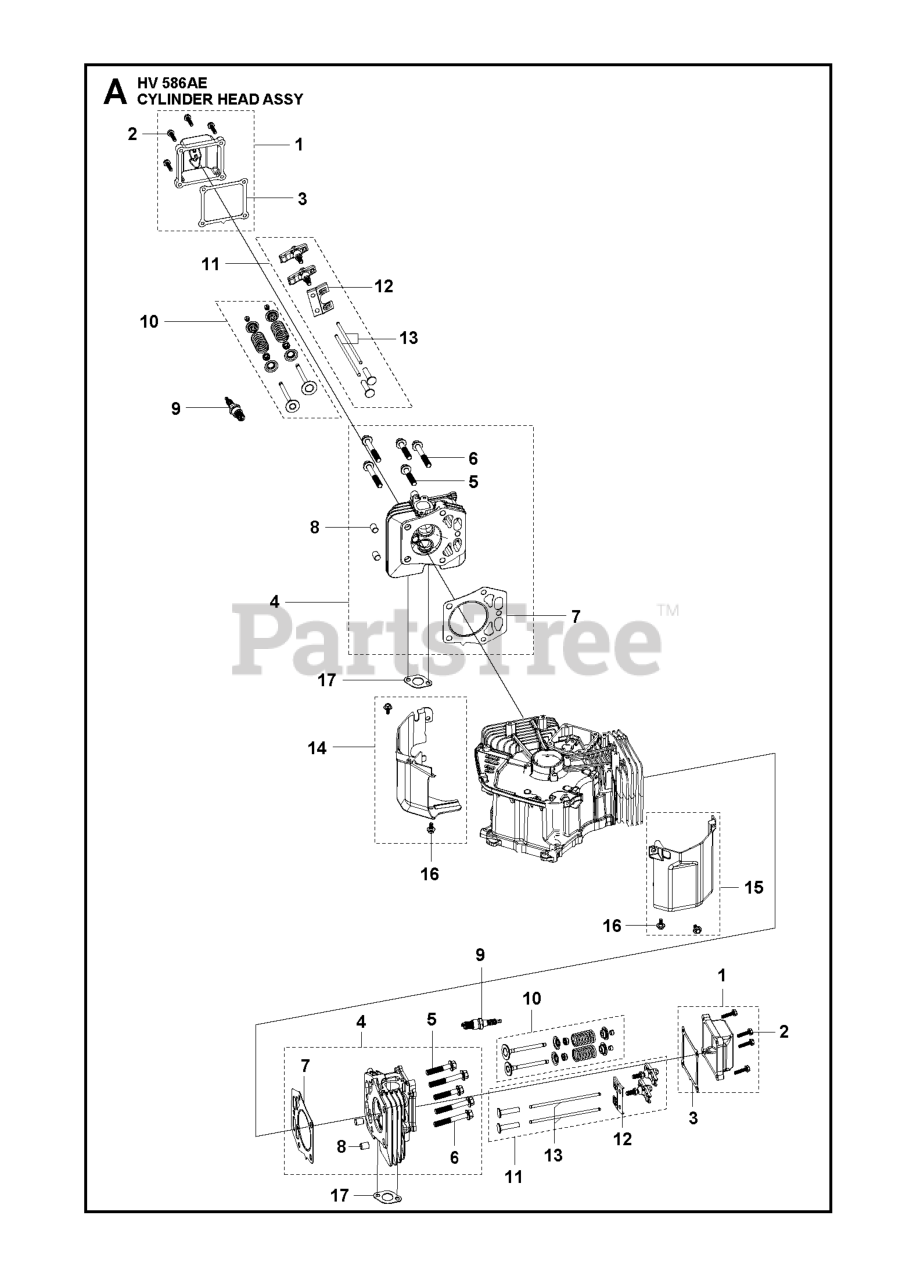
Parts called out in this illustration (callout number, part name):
2	BOLT GB/T 5789: M6 L=25
9	SPARK PLUG HQT-7 RESISTOR
17	EXHAUST GASKET
